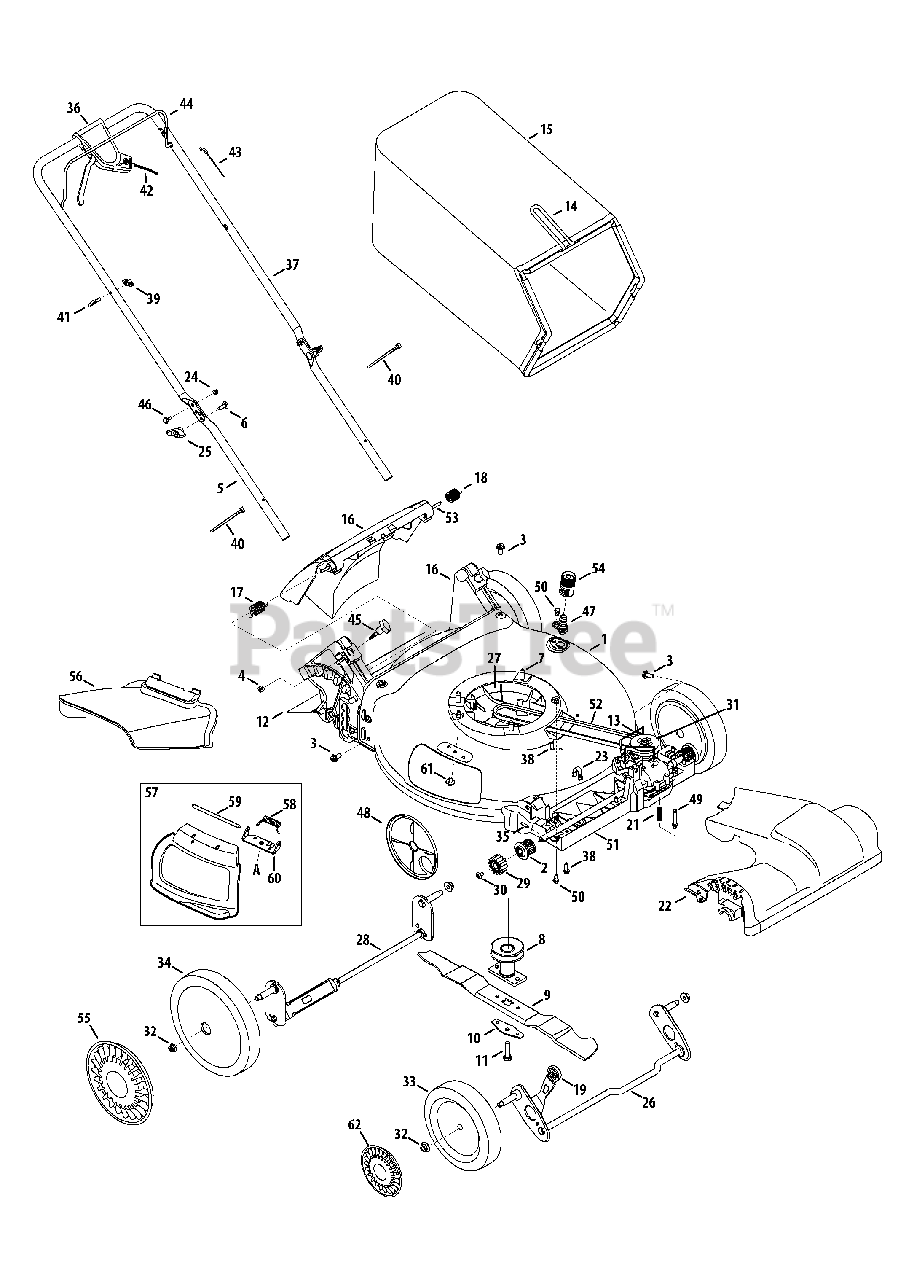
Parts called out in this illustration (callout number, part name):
1	21" Deck Ass’y (w/ side dis. w/nozzle)
2	Bearing Assembly
3	Hex Hd. Cap Scr. 5/16-14 x .75
4	Sq. Nut 1/4-20
5	Lower Handle
6	Carriage Bolt 5/16-18
7	Hex Wash HD Tap Scr 3/8-16 x 1.0
8	Blade Adapter
9	21" Mulching Blade
10	Blade Bell Support
11	Hex Bolt 3/8-24 x 1.5" Lg. (Gr 8)
12	Trailing Shield 4.54 x 17.37
13	Wire
15	Grassbag, Black Dust Blocking
16	Rear Baffle Ass’y (Incl. door)
17	RH Torsion Spring
18	LH Torsion Spring
21	Compression Spring 1.320
22	Front Axle Cover
23	Axle Clip
24	Flanged Lock Nut 1/4-20 Gr. F Nylon
25	Wing Knob
26	Front Axle Ass’y - 8 " wheel
27	Engine Baffle Ass’y
28	Rear Axle Ass’y - 8" wheel
29	Spur Gear 14 T LH
29	Spur Gear 14 T RH
30	Screw 1/4-20 x .390
31	Transmission Ass’y
32	Flange Locknut 3/8-16 Gr. F Nylon
33	Front Wheel
34	Rear Wheel
35	Dowel Pin 3/16 x 3/4
36	Control Lever Ass’y
37	Upper Handle - Black
38	Screw, 1/4-15 x .750
39	Knob 1/4-20
40	Cable Tie
41	Rope Guide Bolt
42	Drive Cable
43	Control Cable
44	Blade Control
45	Knob 1/4-20 x 1.73 Black
46	Shoulder Screw .375 x .126 x 1/4-20
47	Deck Water Nozzle
48	Dust Cover
49	Compression Spring Body
50	Shoulder Scr. 1/4-20 x .50
51	Front SP Tray
52	V Belt
53	Pivot Rod
54	Water Nozzle Adapter
55	Hub Cap (11")
56	Chute Deflector
57	Mulching Plug Ass’y (Incl. ref. no. 58-60)
58	Torsion Spring
59	Hinge Pin
60	Chute Deflector Bracket
61	Screw 1/4-20 x .50
62	Hub Cap
